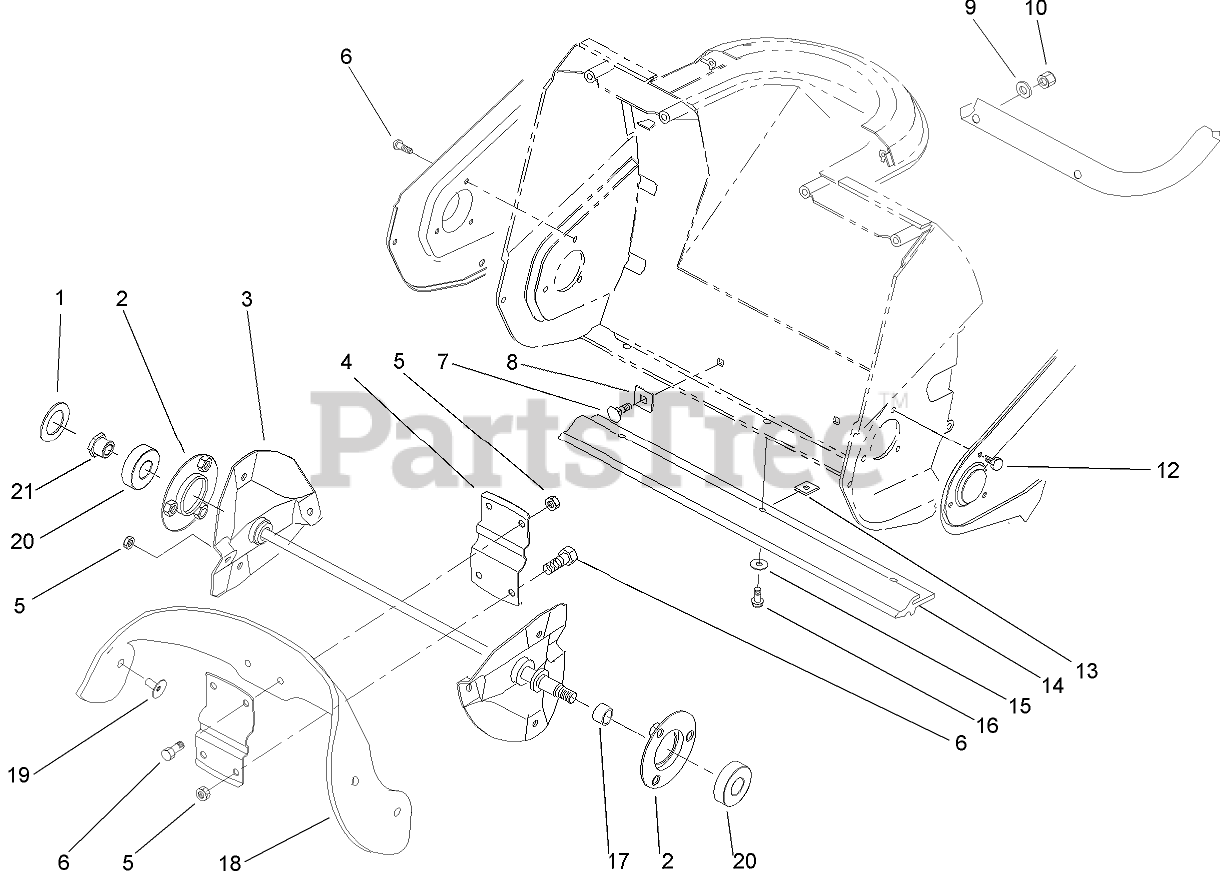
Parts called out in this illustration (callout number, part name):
1	WASHER-RUBBER
2	FLANGE BEARING ASM
3	ROTOR SHAFT ASM
4	SUPPORT-ROTOR
5	NUT-LOCK, NI
6	SCREW-HHF
7	SCREW-CARR
8	WASHER-SQUARE
9	WASHER
10	NUT-LOCK, NI
12	SCREW-HH
13	NUT-CLIP, U
14	SCRAPER
15	WASHER-FLAT
16	SCREW-HWHTF
17	SPACER
18	BLADE-ROTOR
19	SCREW
20	BEARING-BALL
